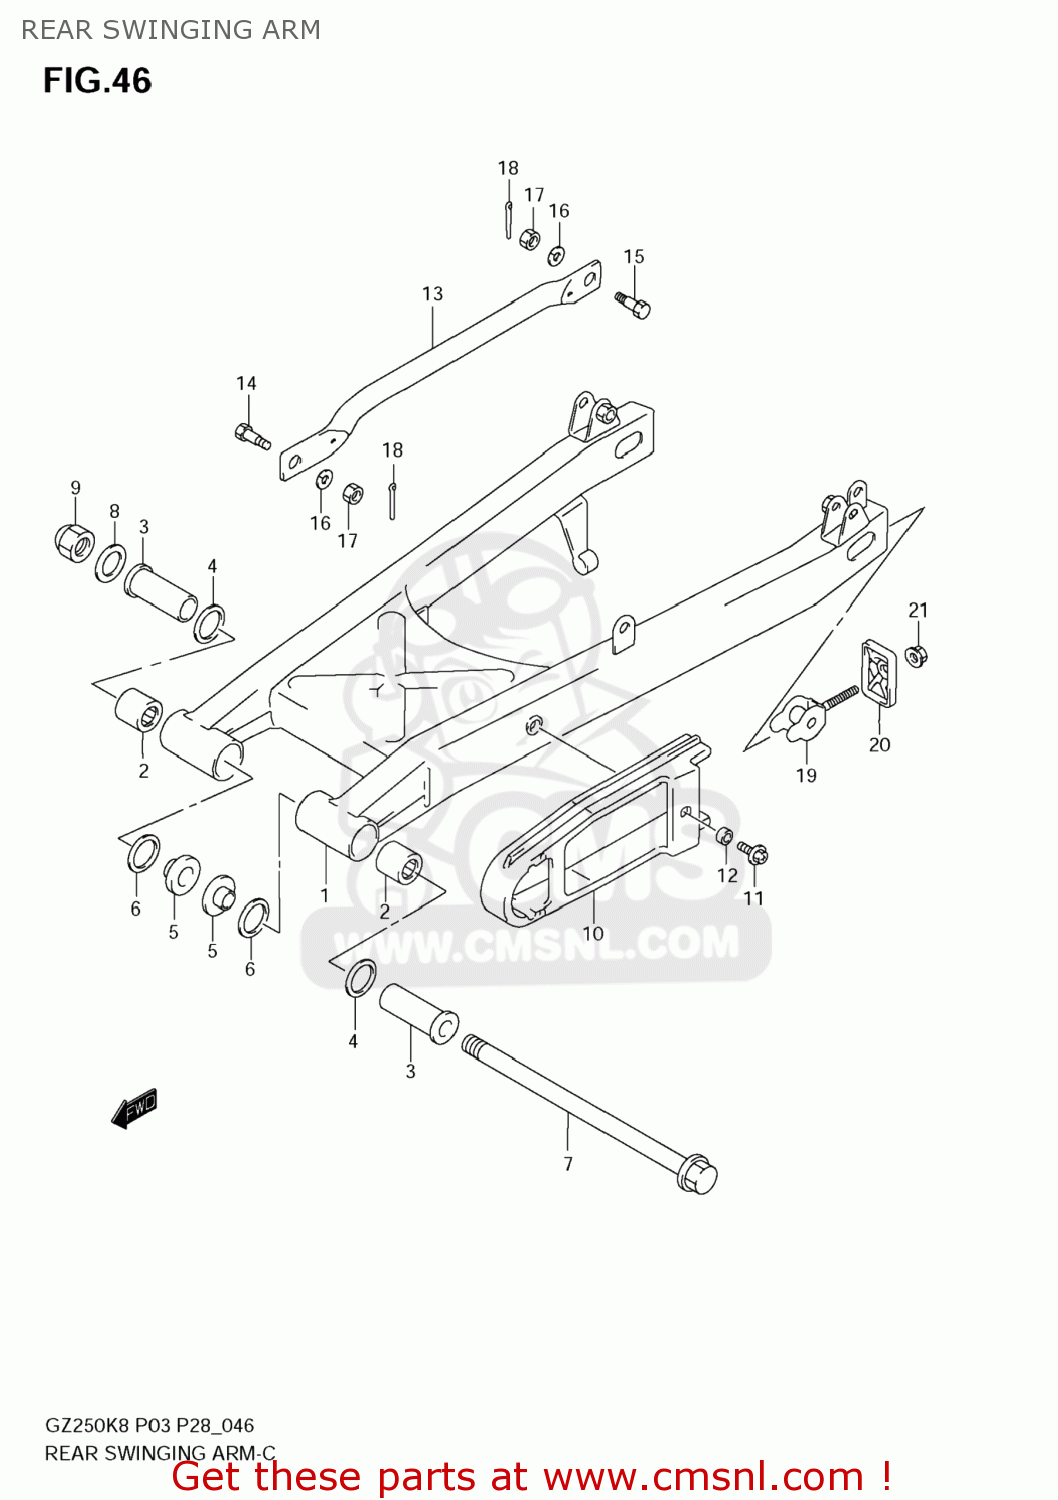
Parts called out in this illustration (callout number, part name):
1	SWINGARM
2	BEARING(20X27X20)
3	SPACER, PIVOT OUTER
4	SEAL,OIL(20X27X5)
5	SPACER, PIVOT INNER
6	SEAL,OIL(20X27X5)
7	SHAFT,RR SWINGINGARM PIVOT
8	WASHER
9	NUT
10	BUFFER,CHAIN TOUCH DEFENSE
11	BOLT 6X20,WITH PLAIN WASHER
12	SPACER(6.5X9X3.8)
13	TORQUELINK,RR
14	BOLT(8X22.5)
15	BOLT(8X26.5)
16	WASHER,LOCK
17	NUT
18	PIN
19	ADJUSTER,CHAIN
20	PLATE,CHAIN ADJUSTER
21	NUT
